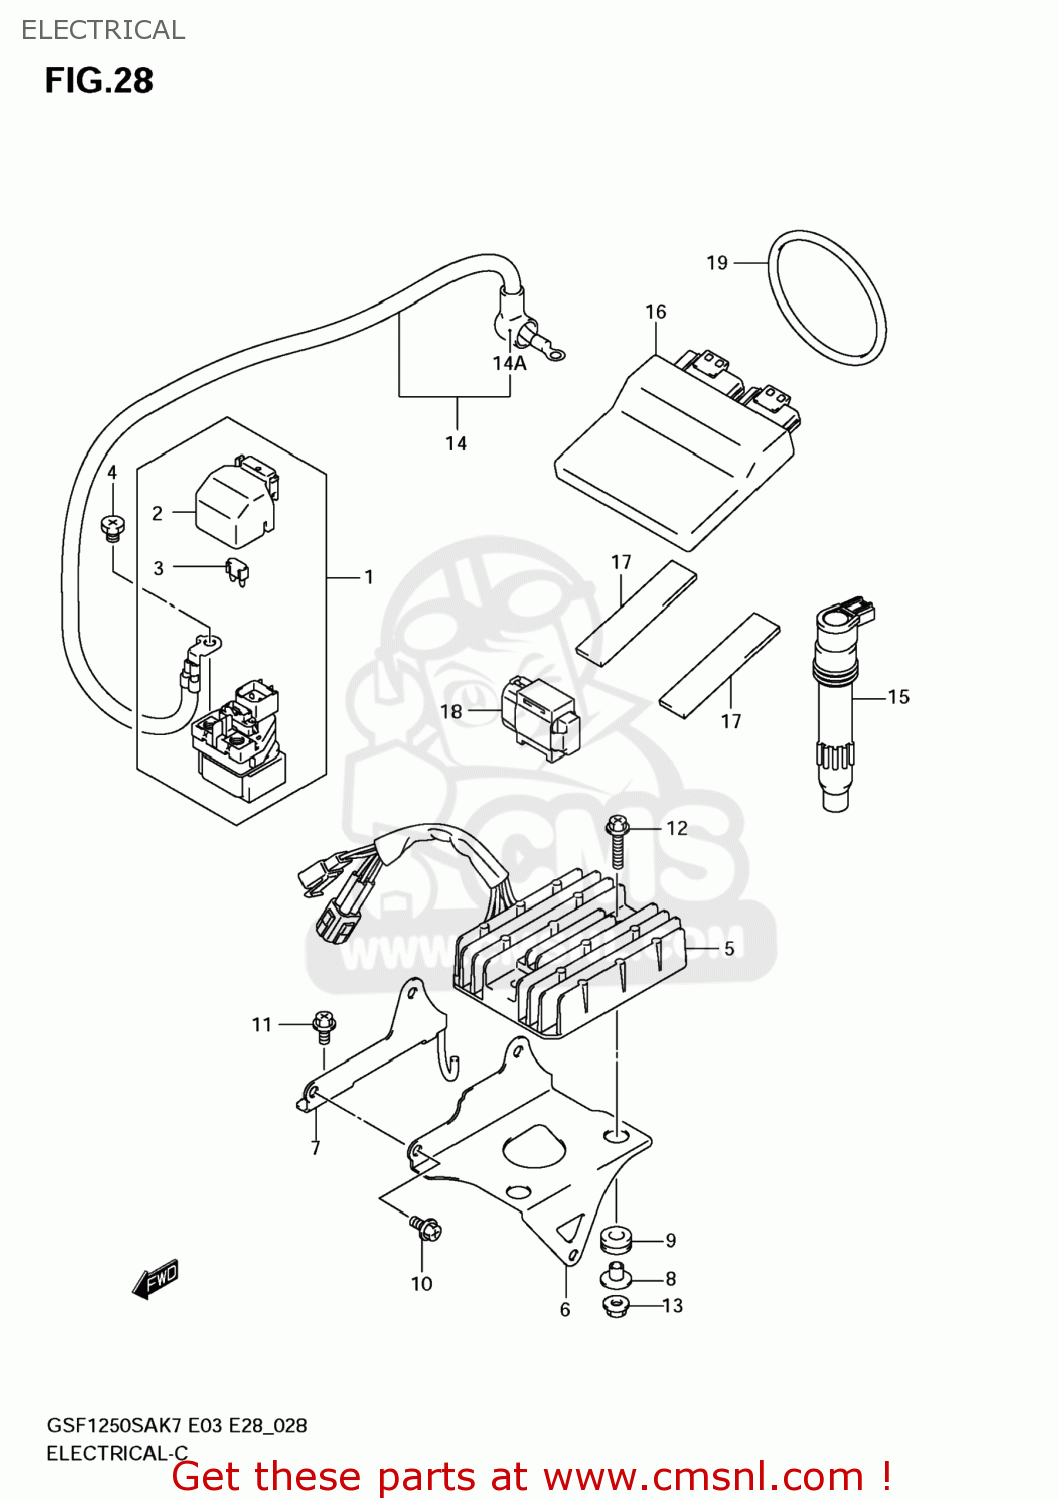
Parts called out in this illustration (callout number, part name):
1	RELAY ASSY
2	COVER
3	FUSE(30A)
4	SCREW(6X8)
5	RECTIFIER ASSY
6	BRACKET,RECT FTG NO.1
7	BRACKET,RECT FTG NO.2
8	SPACER(6.2X8.4X6.9)
9	CUSHION
10	BOLT
11	BOLT
12	BOLT
13	NUT
14	WIRE,STARTER MOTOR LEAD
14A	CAP,STARTER MOTOR
15	COIL ASSY,IGNITION
16	CONTROL UNIT,FI
17	PROTECTOR(20X90)X2
18	SENSOR ASSY,FUEL CUT
19	O RING(D:3.53,ID:69.44)
